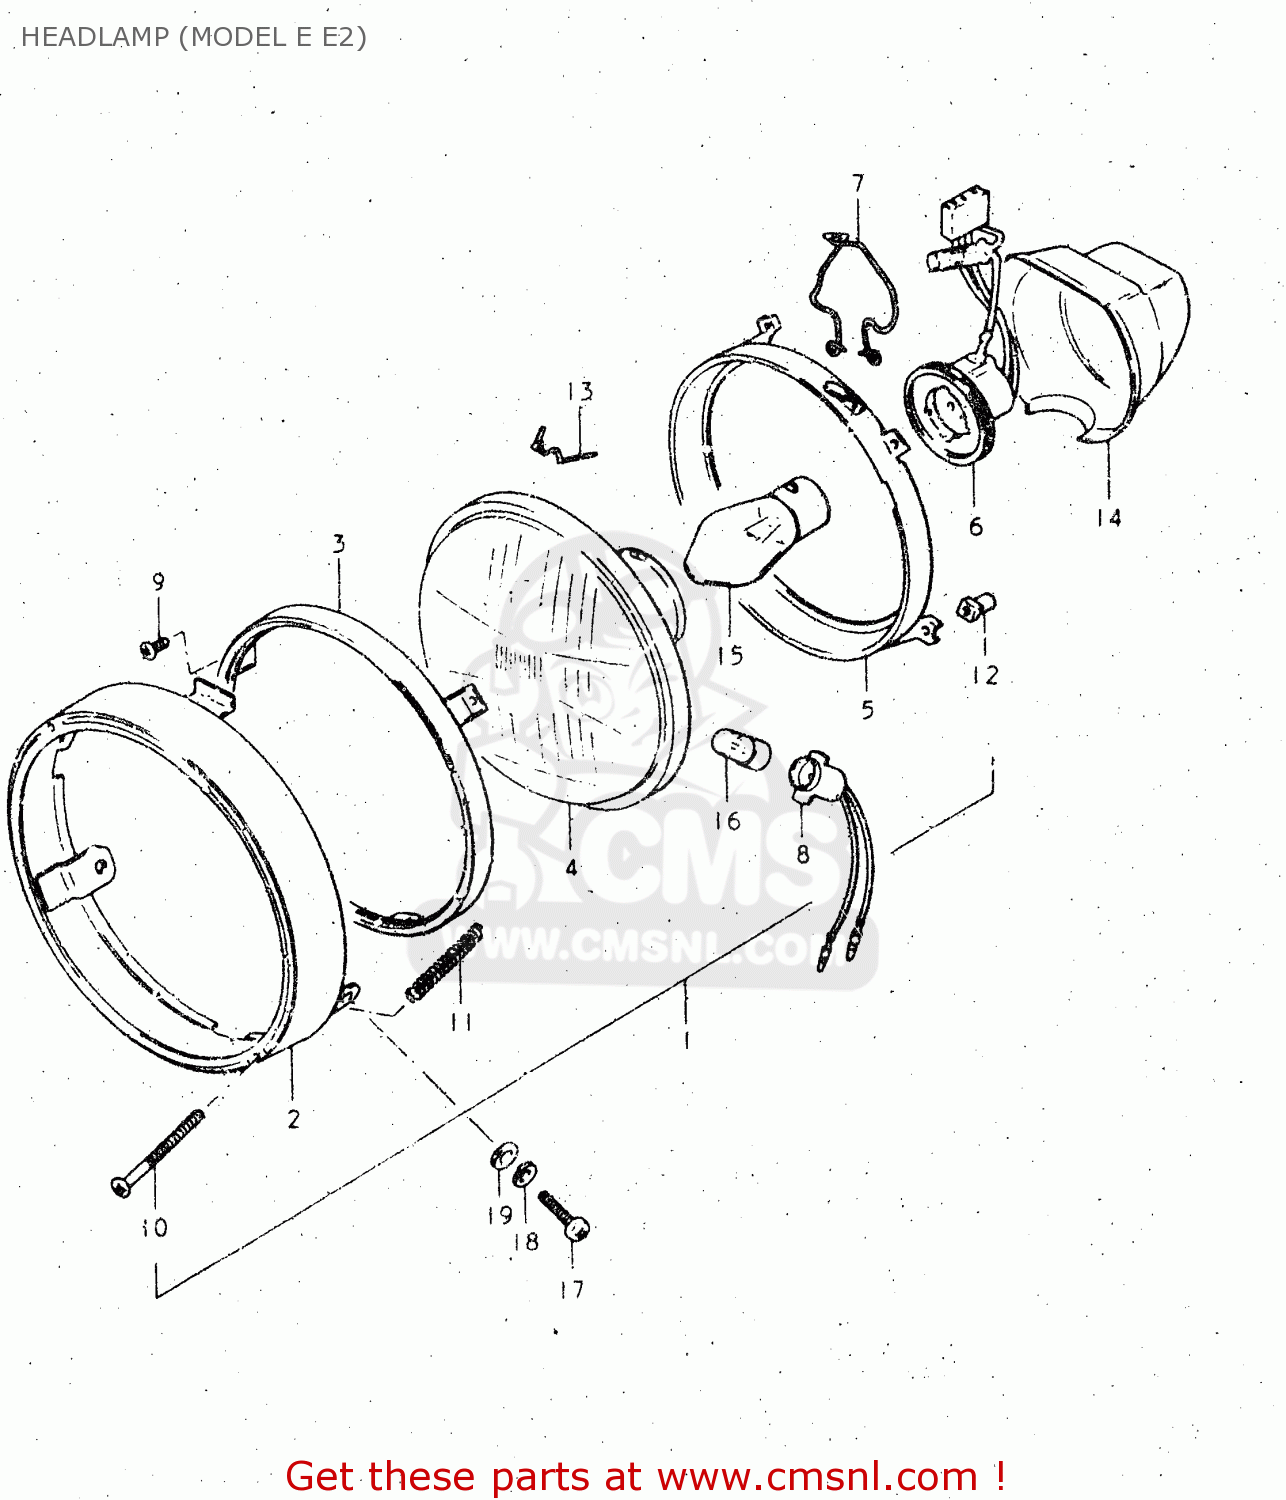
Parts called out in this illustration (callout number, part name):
1	HEADLAMP ASSY
2	RIM
3	RETAINER,HEADLAMP
4	UNIT
5	RING, MOUNTING
6	SOCKET
7	CLAMP,HEADLAMP
8	SOCKET
9	SCREW
10	SCREW,HEADLAMP ADJUST
11	SPRING,ADJUSTING
12	NUT,HEADLAMP ADJUSTER
13	SPRING,HEADLAMP UNIT
14	COVER, SOCKET
15	BULB (6V,35/35W)
16	BULB (6V,4W)
17	SCREW
18	LOCK WASHER
19	WASHER
